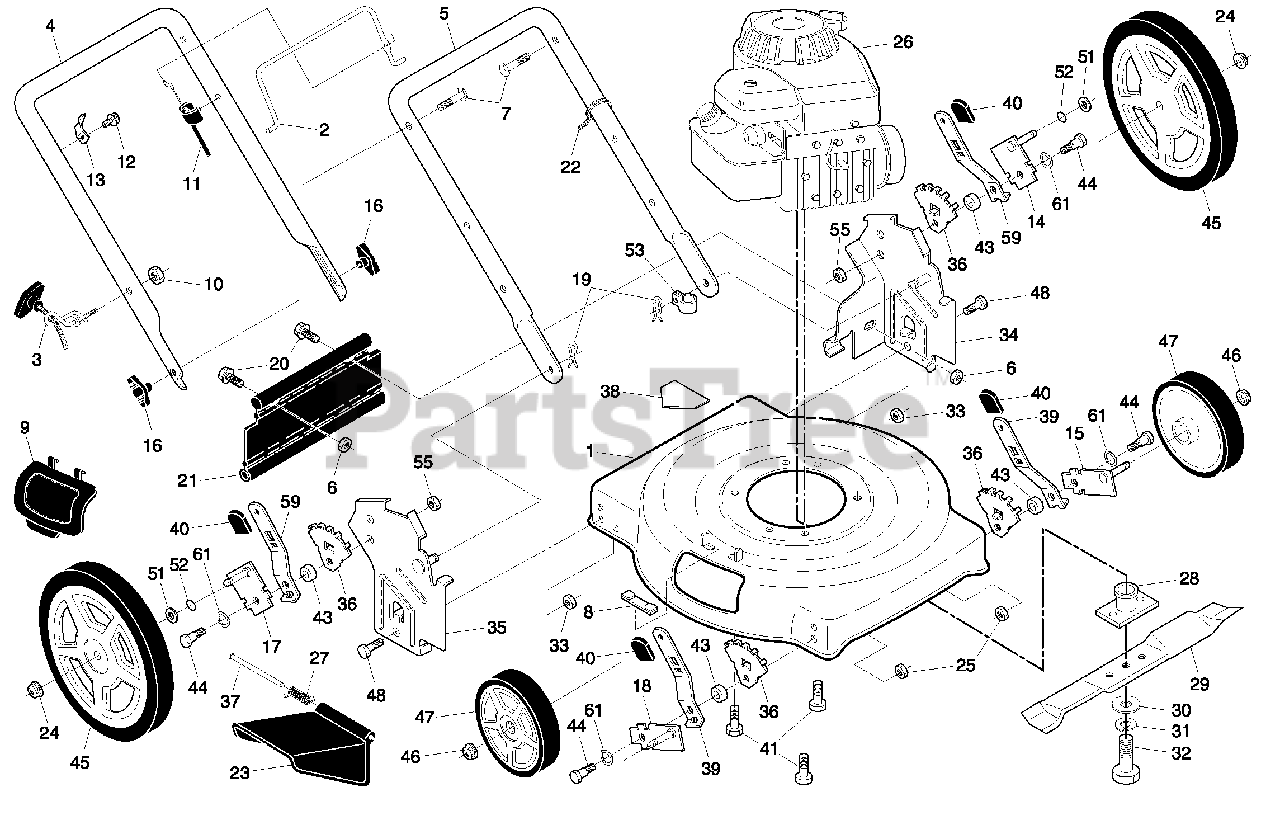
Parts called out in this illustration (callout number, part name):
1	Lawn Mower Housing
2	Control Bar
3	Rope Guide
4	Upper Handle
5	Lower Handle
6	Locknut, Hex 1/4-20
7	Handle Bolt 5/16-18
8	Clip, Closeout
9	Mulcher Plate
10	Nut, Hex 1/4-20
11	Engine Zone Control Cable
12	Hex Washer Head Screw #10-24 x 1/2
13	Up-Stop Bracket
14	Axle Arm Assembly, Rear, LH
15	Axle Arm Assembly, Front, LH
16	Knob, Handle
17	Axle Arm Assembly, Rear, RH
18	Axle Arm Assembly, Front, RH
19	Hairpin Cotter
20	Screw, Hex Cap Head 1/4-20
21	Rear Deflector
22	Wire Tie
23	Discharge Guard
24	Nut, Hex, Flangelock 3/8-16
25	Nut, Hex, Flangelock 5/16-18
27	Torsion Spring
28	Blade Adapter
29	22" Blade
30	Hardened Washer
31	Helical Lockwasher 3/8
32	Screw, Hex Head, Grade 8, 3/8-24 x 1-3/8
33	Nut, Hex, Nylock 5/16-18
34	Handle Bracket, LH
35	Handle Bracket, RH
36	Wheel Bracket Adjuster
37	Hinge Rod
38	Danger Decal
39	Selector Spring, Front
40	Selector Knob
41	Screw, Hex Head, Threaded, Rolled 3/8-16 x 1
43	Spacer
44	Shoulder Bolt 5/16-18
45	Wheel & Tire Assembly, Rear, 12"
46	Nut, Hex, Flangelock 3/8-16
47	Wheel & Tire Assembly, Front, 8"
48	Bolt, Hex Head 5/16-18
51	Washer, Flat 3/8
52	O-Ring
53	Clip, Cable
55	Nut, Hex
59	Selector Spring, Rear
61	Washer, Curved, Cylindrical
61	Operator’s Manual, English
61	Operator’s Manual, Spanish
61	Repair Parts Manual
